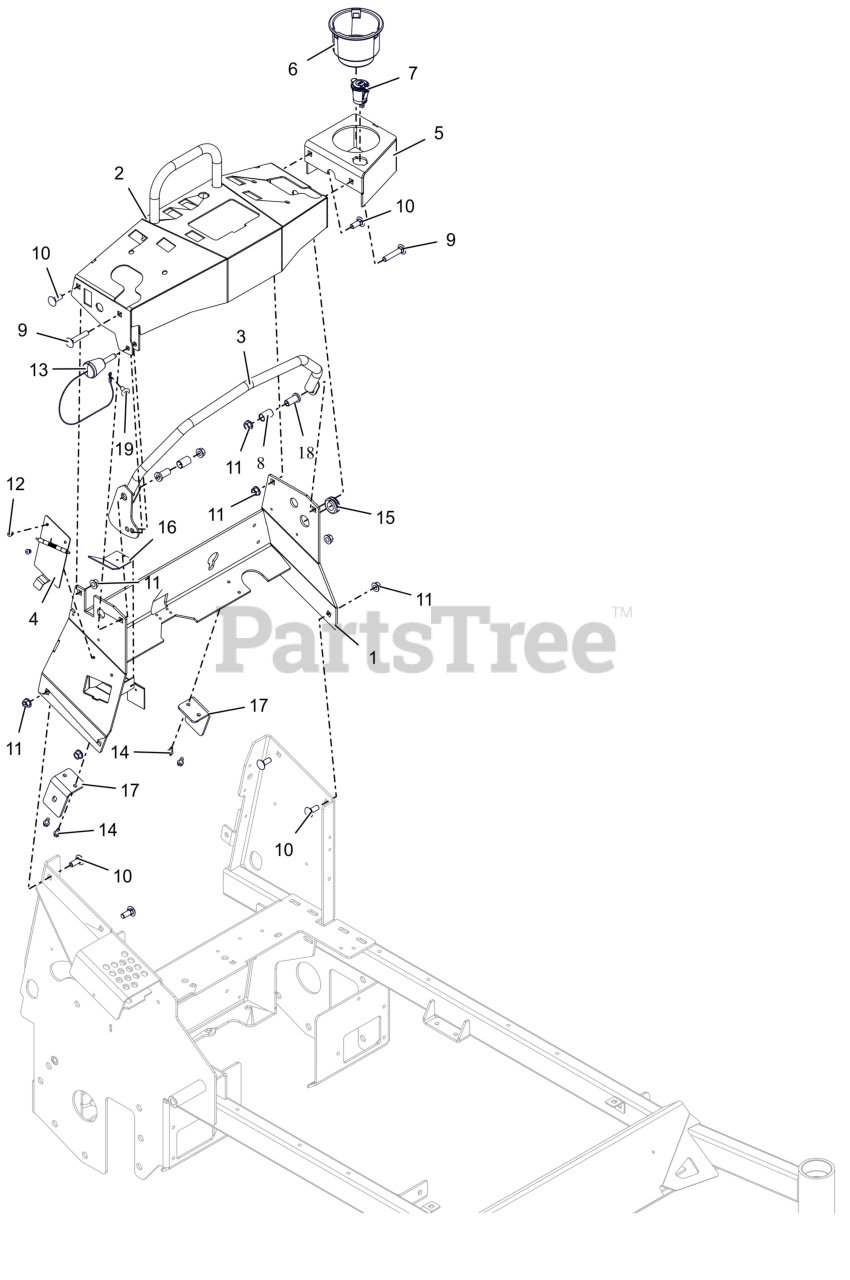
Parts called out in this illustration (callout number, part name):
1	WLDMT- TOWER
2	WLDMT- DASH
3	WLDMT, CRUISE BAR (BLACK)
4	ASM, CHARGER COVER
5	WLDMT- CUP HOLDER
6	CUPHOLDER, SNAP-IN 3.75OD
7	PORT, 12 VOLT POWER
8	BRG, .500 x .625 x1.000
9	BLT, RHSN .38-16X2.00 G5 ZCC
10	BLT, RHSN .38-16X1.00 G5 ZCC
11	NUT-LK-CTR-FLG .375-16 GF ZCC
12	RVT, .1875 AL .063-.250 HD BLK
13	PIN- MAGNETIC .375 X 1.5
14	SCR-TAP .25-20X.50 HWH ZCC
15	GROMMET, RUBBER .688 ID X 1.000 X .500 X 1.313
16	COVER, CHARGER BRACKET (ORANGE)
17	BRKT- DAMPER MTG
18	BSHG, FLANGED
19	XMAS TREE FASTNER-BLACK
